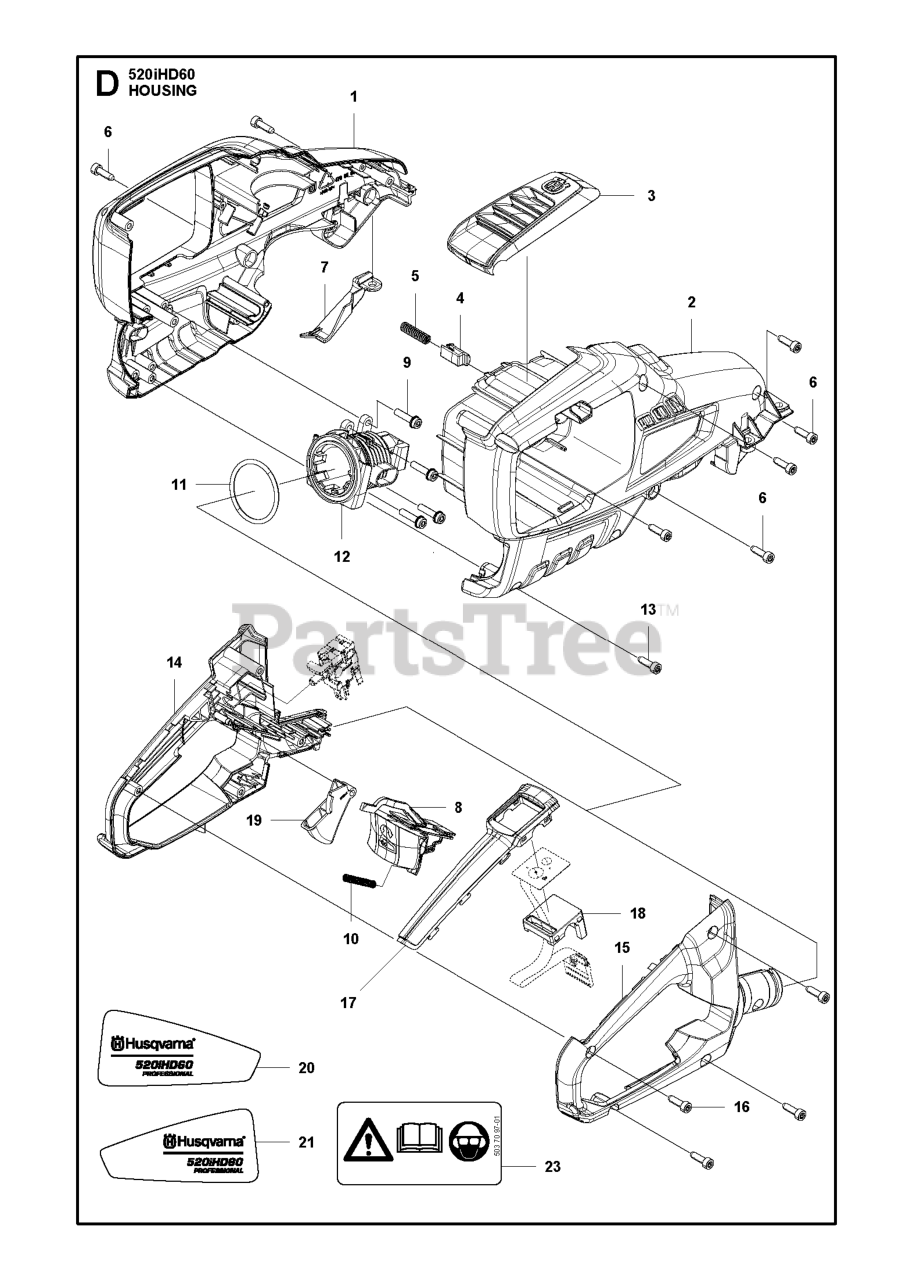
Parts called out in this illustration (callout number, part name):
1	CHASSIS LEFT
2	CHASSIS RIGHT
3	COVER CHASSIS
4	PUSH BUTTON
5	SPRING
7	COVER WIRING
8	LOCKING BUTTON
9	SCREW IHSCFT
10	RECOIL SPRING RECOIL SPRING RE
12	HANDLE HOLDER
13	SCREW
14	REAR HANDLE LEFT
15	REAR HANDLE RIGHT
16	SCREW
17	FRAME KEYPAD
18	BRACKET KEYPAD
19	THROTTLE CONTROL
20	DECAL PRODUCT RIGHT 520IHD60
21	DECAL PRODUCT LEFT 520IHD60
